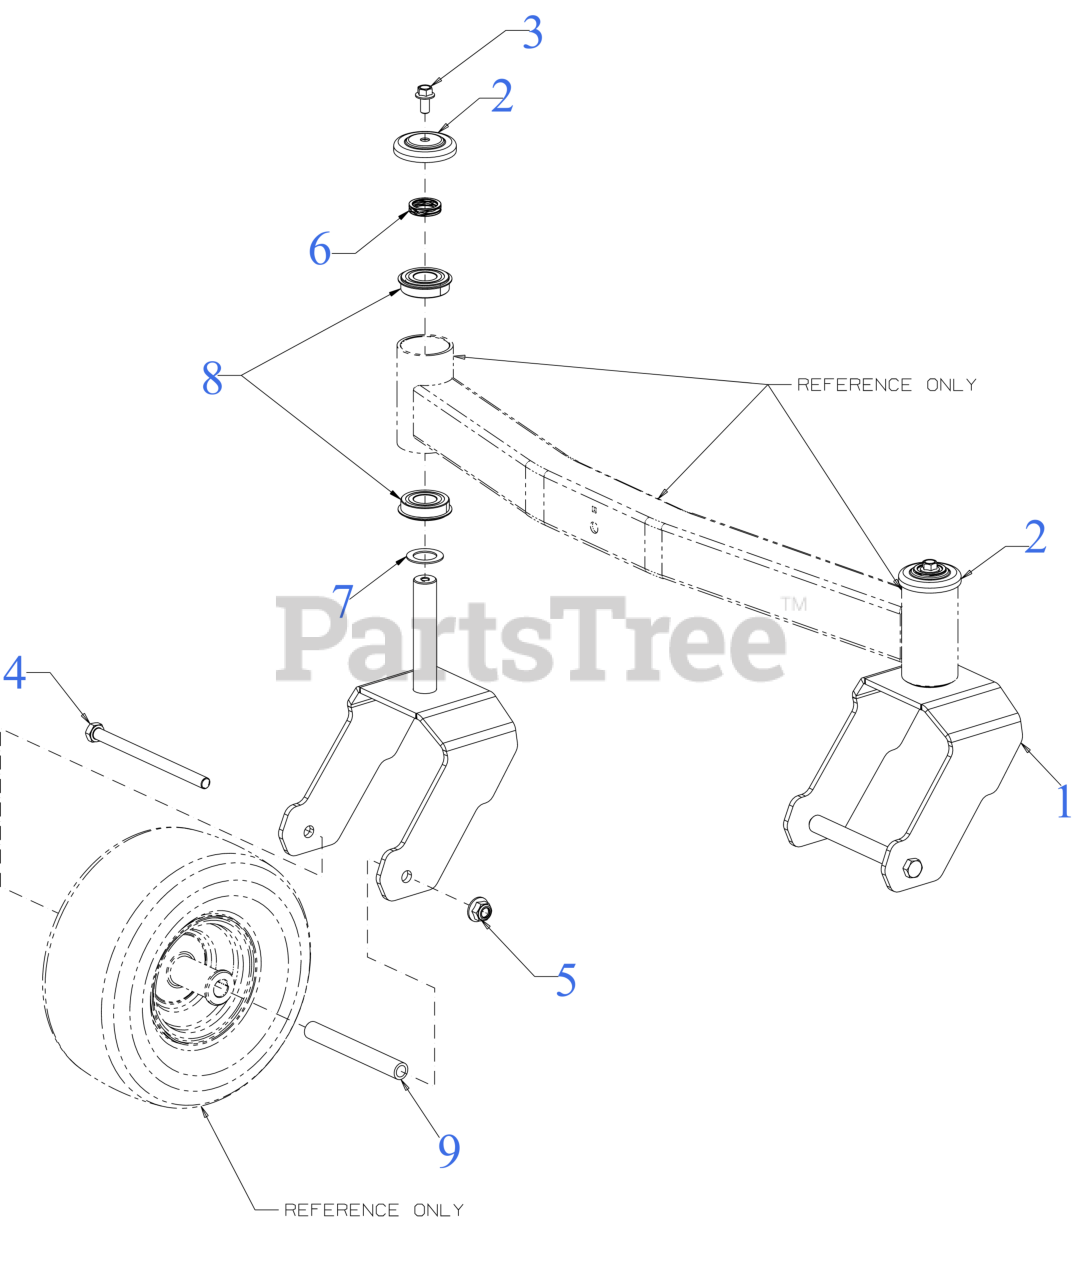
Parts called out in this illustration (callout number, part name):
1	CASTER WHEEL YOKE
3	BOLT - 3/8-16:.75:GR5:PATCH LOCK
4	HEX HEAD CAP SCREW 1/2 13-7.25 GR5
5	NUT
6	WAVE WASHER
7	WASHER 1.010X1.560X.060
8	BALL BEARING 25X52X15
9	CASTER AXLE SPACER
